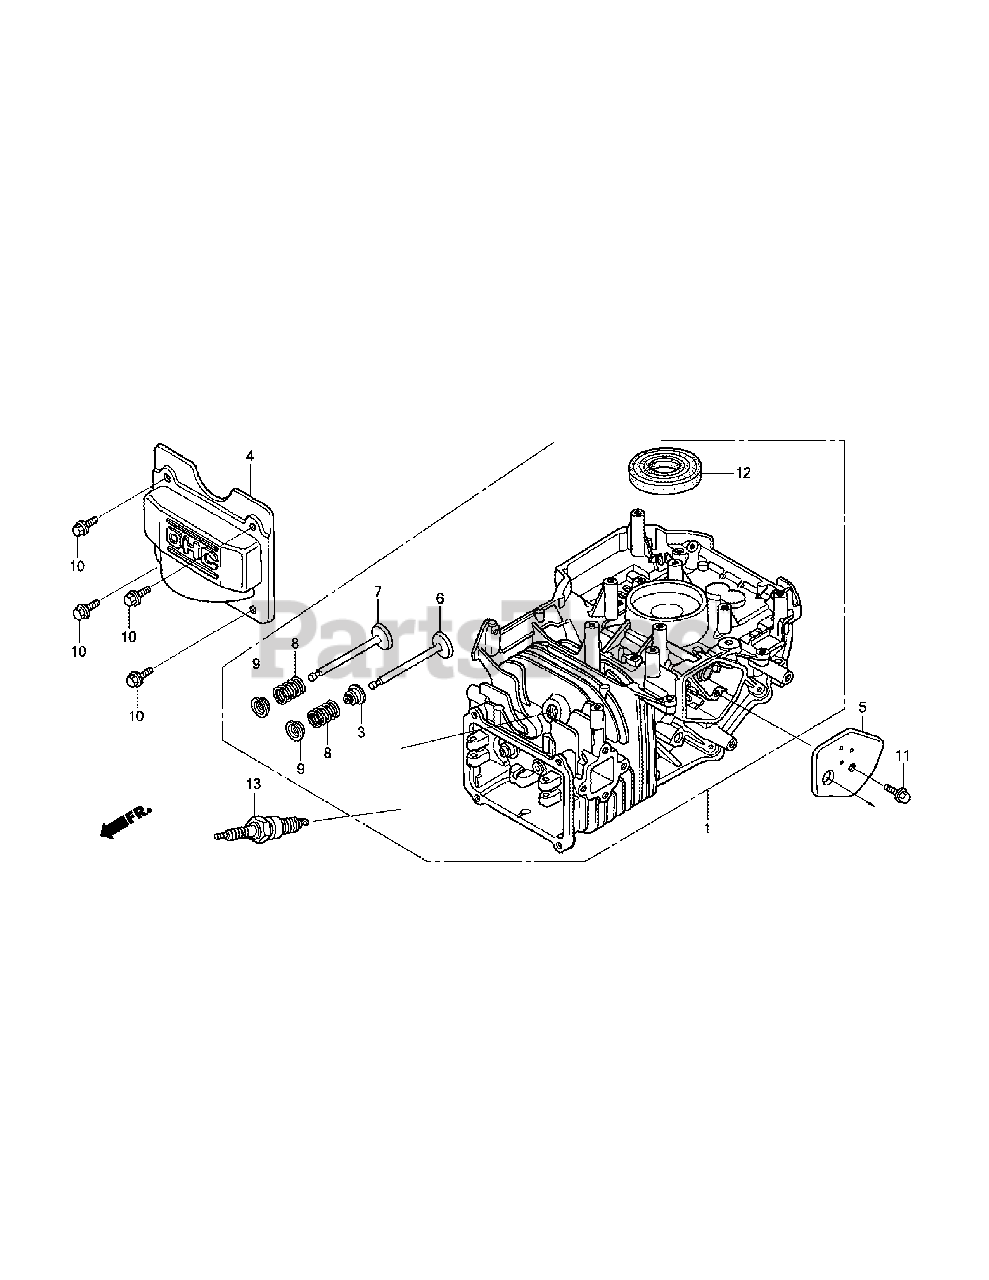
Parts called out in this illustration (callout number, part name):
1	Cylinder Assembly
3	Valve Stem Seal
4	Head Cover
5	Cover, Breather
6	Intake Valve
7	Exhaust Valve
8	Valve Spring
9	Valve Spring Retainer
10	Flange Bolt, 6 x 12
11	Flange Bolt, 6 x 14
12	Oil Seal, 25.4 x 62 x 6
13	Spark Plug, BPR6ES
